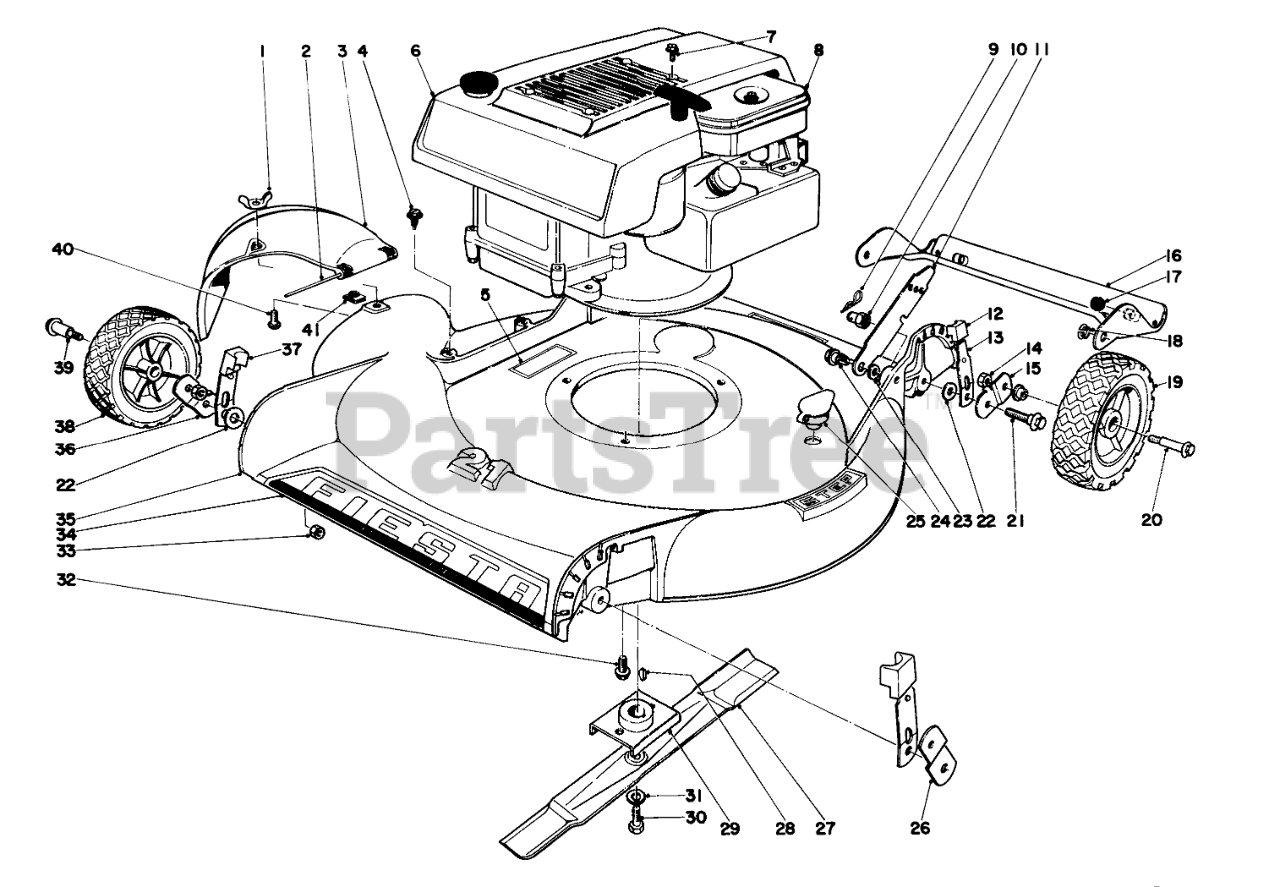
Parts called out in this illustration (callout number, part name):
1	NUT-WING SPECL
2	HINGE PIN
3	Deflector
4	SCREW-HWHTF
5	Decal, Warning
6	Shroud, Model #16000
7	8X1/2 SELF TAP SCREW
8	Engine, Model #16000
9	PIN-COTTER, HAIR
10	Nut
11	Handle Latch
12	Arm Knob
13	Spring Arm
14	Nut
15	Pivot Arm
16	Rear Safety Shield (Incl. Ref. #17, Model #16000)
17	SKID BUTTON
18	Nyliner
19	WHEEL ASM 8
20	Wheel Bolt
21	Pivot Screw
22	Pivot Washer
23	SPACER
24	SCREW-SHOULDER
25	WASHOUT PLUG
26	Pivot Arm
27	Blade, Model #16000
28	KEY-WOODRUFF
29	Blade Retainer
30	SPECIAL SCREW
31	WASHER-LOCK
32	SCREW-HWHTF
33	Nut
34	Decal, Model #16000
35	Housing, Model #16000
36	Pivot Arm
37	Arm Knob
38	WHEEL ASM 7
41	NUT-SPEED
